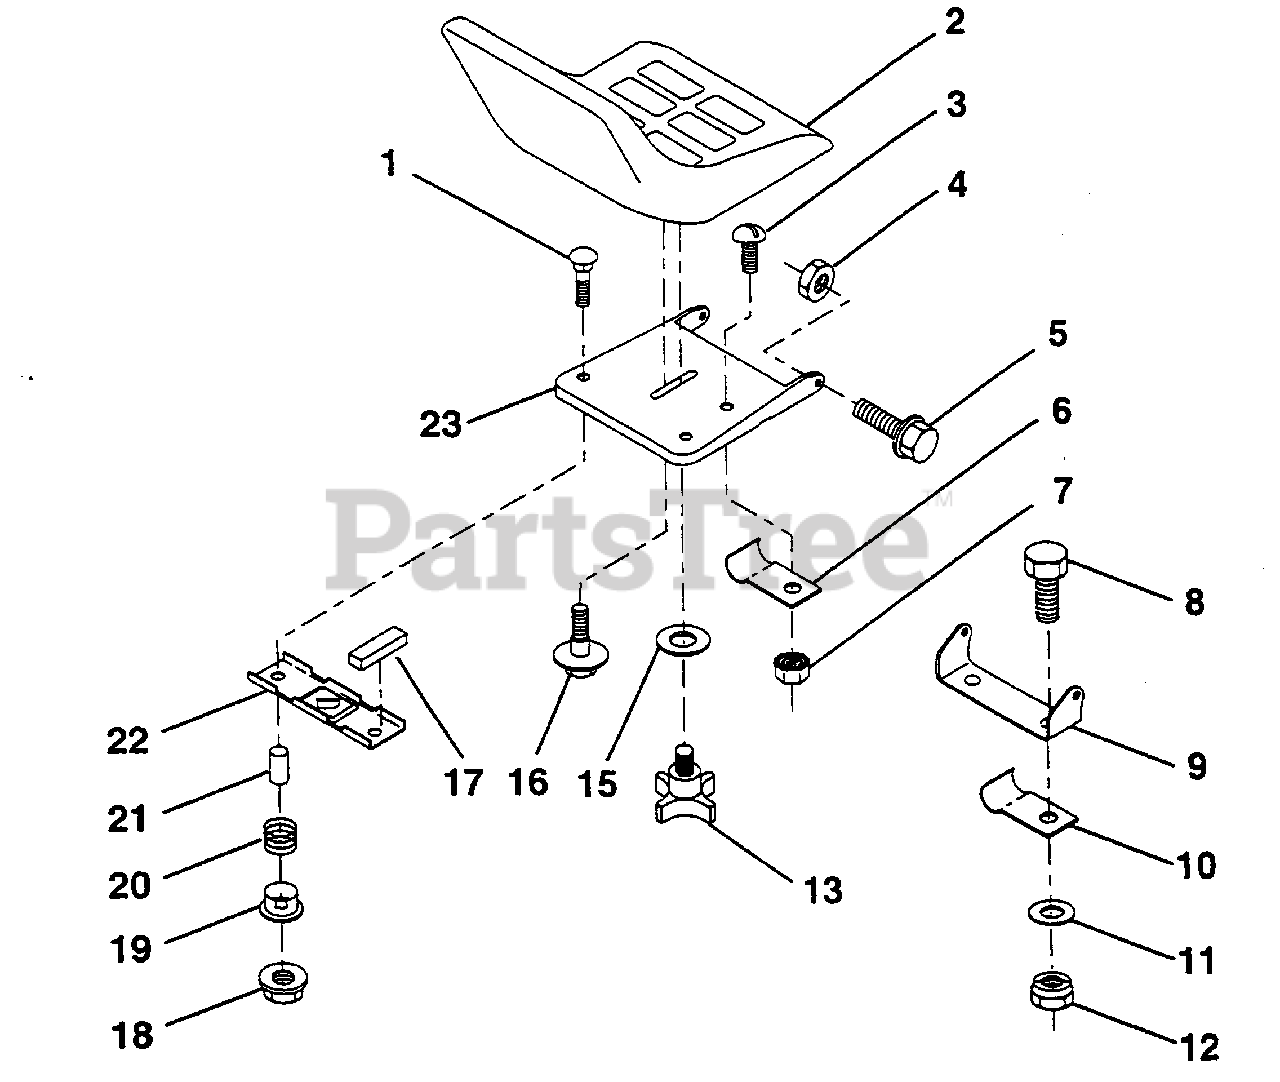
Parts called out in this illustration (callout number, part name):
1	Bolt, Carriage 1/4-20 x 1-3/8
2	Seat (AYP part number)
3	Screw, Slotted Pan Head #10-32 x 1/2 (AYP part number)
4	Nut, Crownlock 5/16-18
5	Bolt, Shoulder 5/16-18 UNC (AYP part number)
6	Clip, Insulated (AYP part number)
7	Nut, Hex, Keps #10-32 UNF (AYP part number)
8	Bolt, Hex, Fin. 3/8-16 UNC x 3/4 (AYP part number)
9	Bracket, Pivot, Seat (AYP part number)
10	Clip, Insulated (AYP part number)
11	Washer 13/32 x 2 x 10 Gauge (AYP part number)
12	Nut, Crownlock 3/8-16 UNC
13	Knob, Adjustment, Seat (AYP part number)
15	Washer 17/32 x 1-3/16 x 12 Gauge (AYP part number)
16	Bolt, Shoulder (AYP part number)
17	Strip, Foam (AYP part number)
18	Locknut, Hex, Flange, Large (AYP part number)
19	Bushing, Snap (AYP part number)
20	Spring, Compression (AYP part number)
21	Spacer, Split, Large .28 Id. x .96 (AYP part number)
22	Bracket, Switch Mounting (AYP part number)
23	Pan, Seat (AYP part number)
